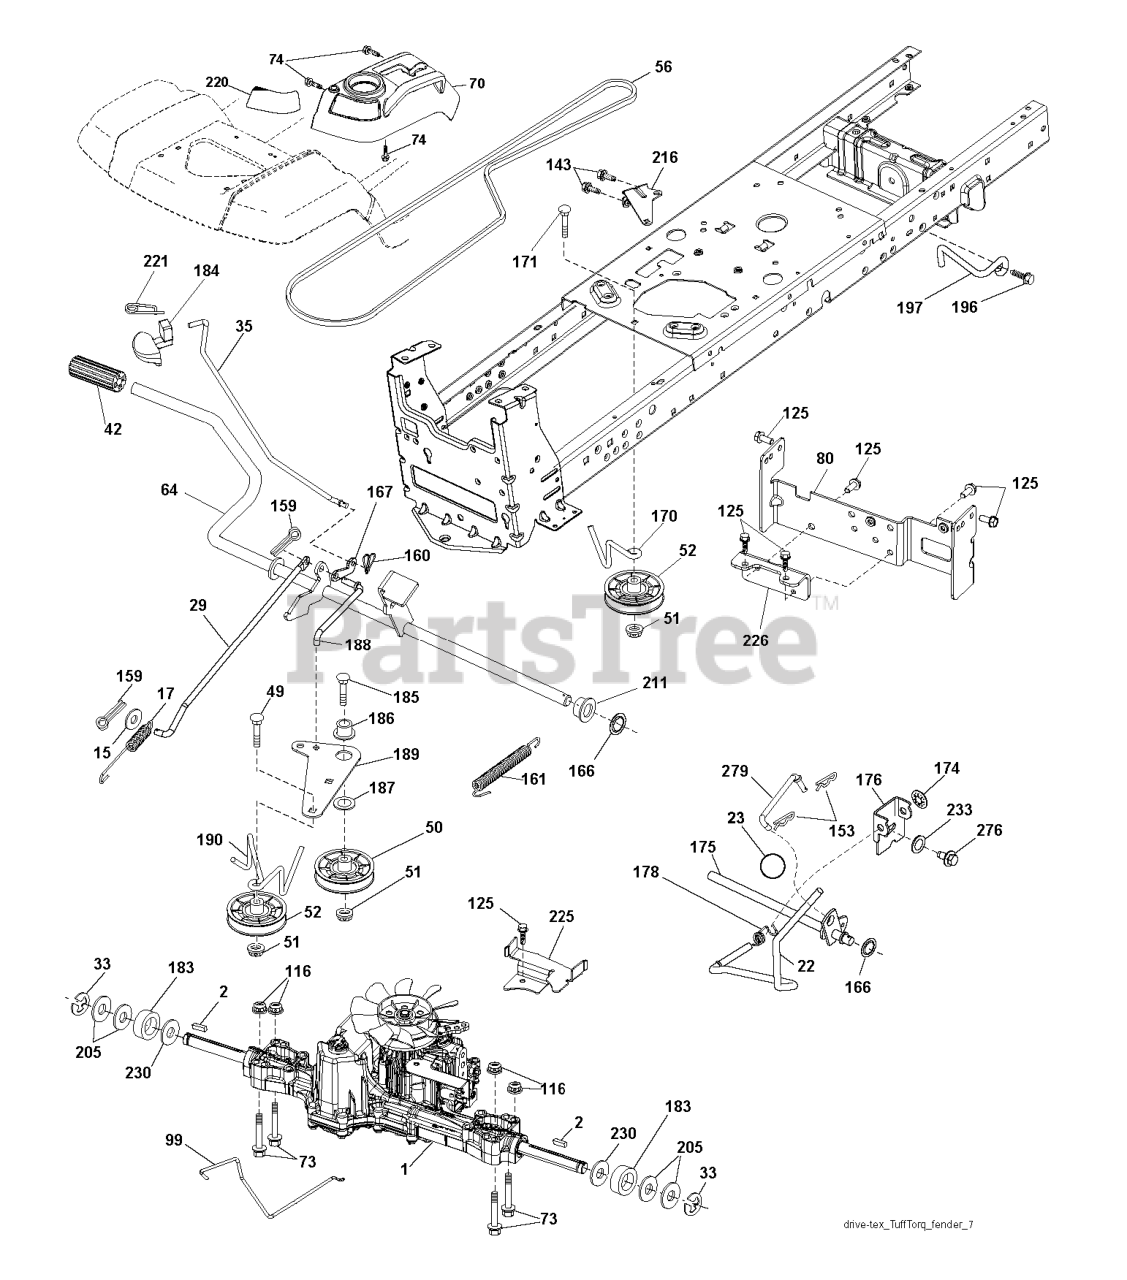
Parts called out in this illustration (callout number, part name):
2	SQUARE KEY
15	WASHER
17	SPRING.BRAKE.K46.GREEN
22	ROD.SHIFT.FENDER.STGT.
23	KNOB.DUCKHEAD.1/2
29	ROD.BRAKE.K46
35	ROD.BRAKE.PARKING.GT.H
42	PEDAL COVER T
50	IDLER.FLAT.910.OFFSET
51	NUT LOCK FLG 3/8-16 UNC
52	IDLER.V-GROOVE.910.OFFSET
56	V-BELT.MOWER.92.40.42/K46
64	SHAFT.ASM.PEDAL.BRAKE.
70	RP CONSOLE.ASM.HYDO.HUSQ.
73	BOLT HEX 5/16-18 GR 5
74	SCREW.HI-LO.CONSOLE
80	STRAP TORQUE
99	ROD.SPRING.BYPASS.K46.LT.Z
116	NUT LOCK HEX FLANGE 5/16-18
125	SCREW
143	Screw 5/16-18 x 1/2 Hex, Self Tapping 5/16-18 x 1/2
153	RETAINER M
159	COTTER PIN
160	RETAINER CLIP
161	SPRING, RETURN LT
166	NUT.PUSH.625.2006
167	LATCH.BRAKE.SPRING
170	KEEPER.V-IDLER.CENTER.
174	NUT.PUSH.500.2006
175	SHAFT ASM SHIFT
176	ARM.CLEVIS.ROD.SHIFT
178	SPRING.SHIFT.GT2006
183	SPACER AXLE
184	HANDLE.PARKG.BRK.HUSQ X667
186	SPACER.RETAINER
187	WASHER 12/32X2X10GA
188	RP.LINK.CLUTCH.GROUND.DRIVE
189	BELLCRANK.GROUND.DRIVE.TEX.
190	KEEPER.BELLCRANK.DRIVE
196	SCREW 3/8-16X1
197	LINK.CLUTCH.ANIT-ROTAT
211	BUSHING.SHAFT.BRAKE.HAND
216	BRACKET.PULLEY.IDLER.W/TEX
220	REFLECTOR.RH.TEX GT
221	RETAINER.SPRING.CLIP.H
225	KEEPER.BELT.TRANSAXLE.K46
226	BRACKET.MOUNT.TORQUE.K46.TLT
230	WASHER.HARDENED
233	WASHER SERRATED
276	BOLT FIN HEX 7/16-14 X 1
279	LINK.SHIFT.T/A.K46.FEND.TX
